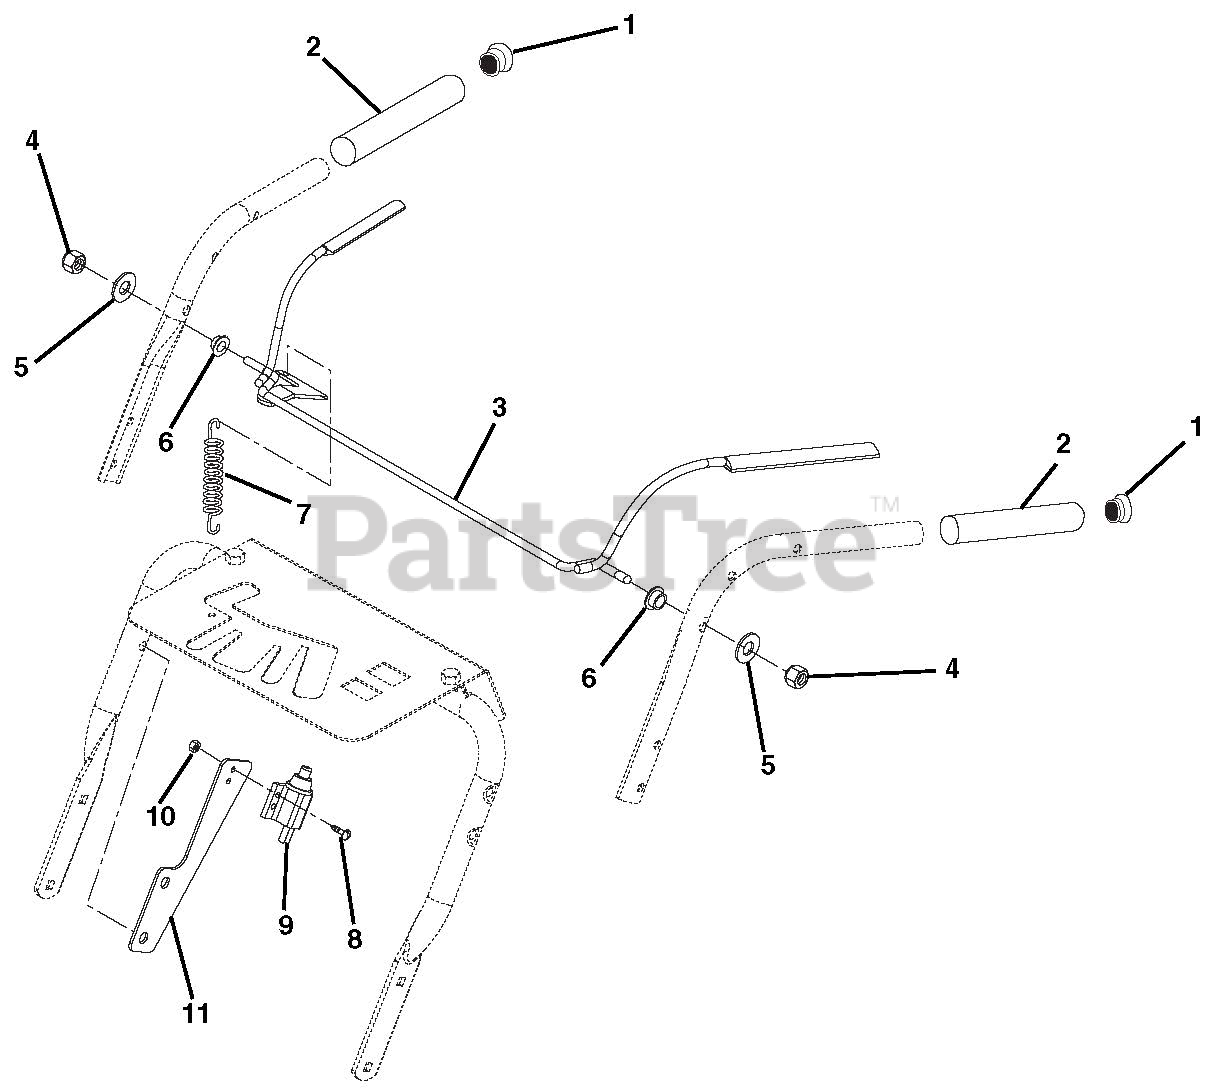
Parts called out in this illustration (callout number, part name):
1	Cap-Vinyl
2	Grip-Handle
3	Weldment, Rod
4	Nut-Locking-Center .31-18
5	Washer-Flat-Steel .344 x .688 x .065
6	Bushing-Flange
7	Spring-Tension .041 x .50 x 1.75
8	Screw-Machine 10-24 x .75
9	Switch-SinglePole N.O. with Cover
10	Nut-Locking-Nylon 10-24
11	Bracket-Switch Mounting
